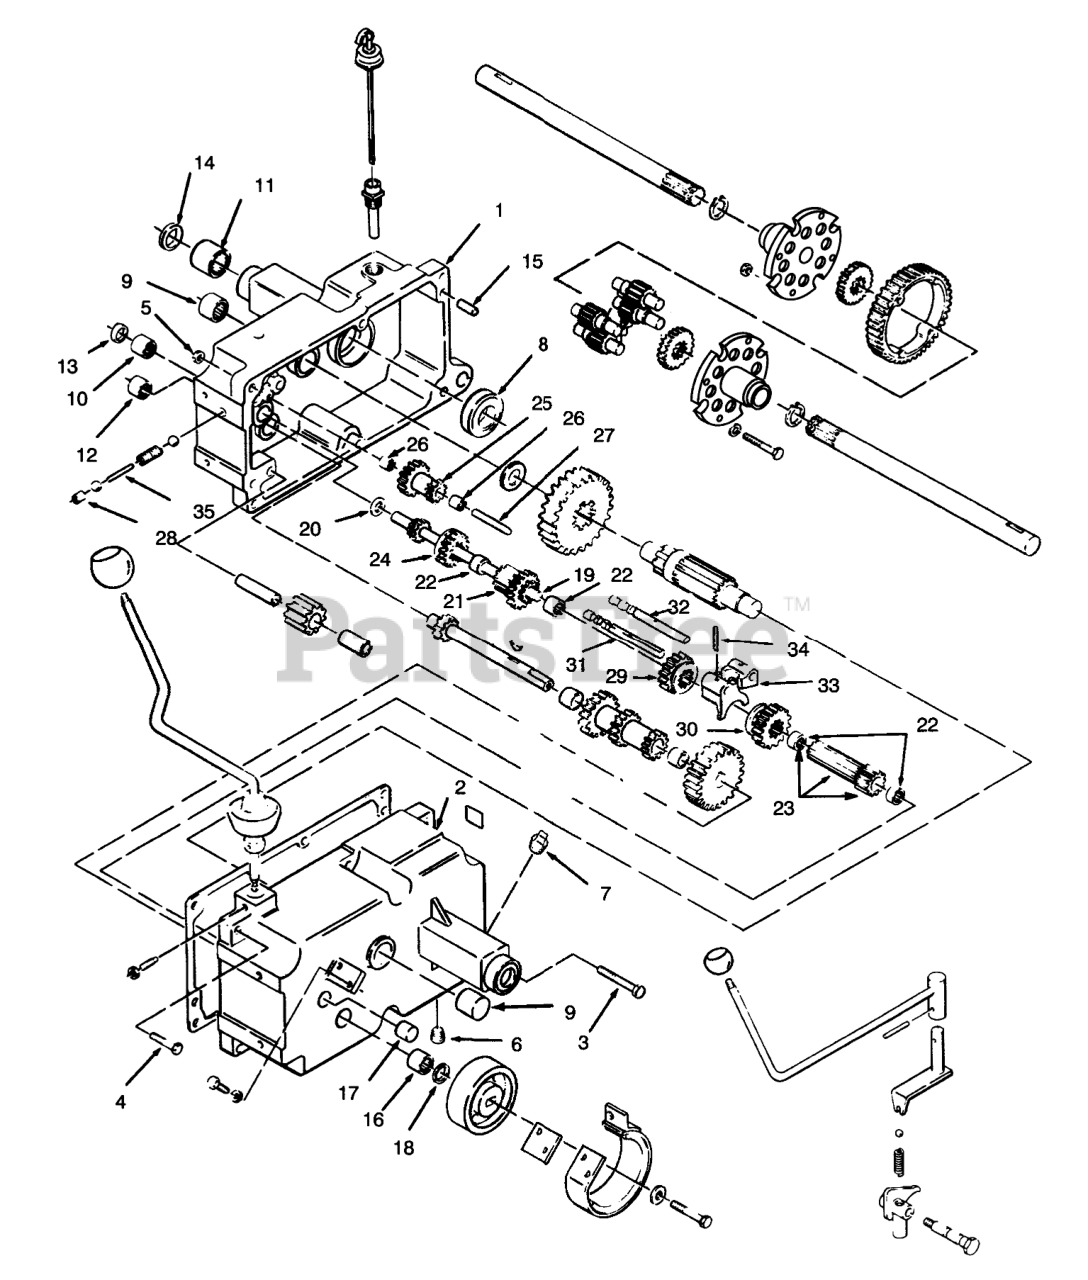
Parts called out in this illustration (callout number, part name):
1	Case Trans RH
2	Case Trans LH
3	SCREW-HH
4	SCREW-HH
5	NUT-LOCK, NI
7	PLUG-PIPE, SQH
8	BEARING-BALL
9	BEARING-NEEDLE
10	BEARING-NEEDLE
11	BEARING
12	BEARING-NEEDLE
13	SEAL-OIL
14	SEAL-OIL
15	PIN-DOWEL
16	BEARING-NEEDLE
17	BEARING-NEEDLE
18	SEAL-OIL
19	SHAFT-INPUT
20	WASHER-THR
21	Gear Assembly (Incl. Ref. #22)
22	BEARING-NEEDLE
23	Gear Assembly (Incl. Ref. # 22)
24	GEAR-SLIDING
25	Gear
26	BEARING-NEEDLE
27	GEAR-SHAFT REDUCTION
28	CUP-PLUG
29	GEAR-HI AND 2ND
30	GEAR-LOW AND REVERSE
31	RAIL-SHIFT
32	RAIL-REAR SHIFT
33	FORK-SHIFT
34	PIN-ROLL
35	PIN-SHIFT
